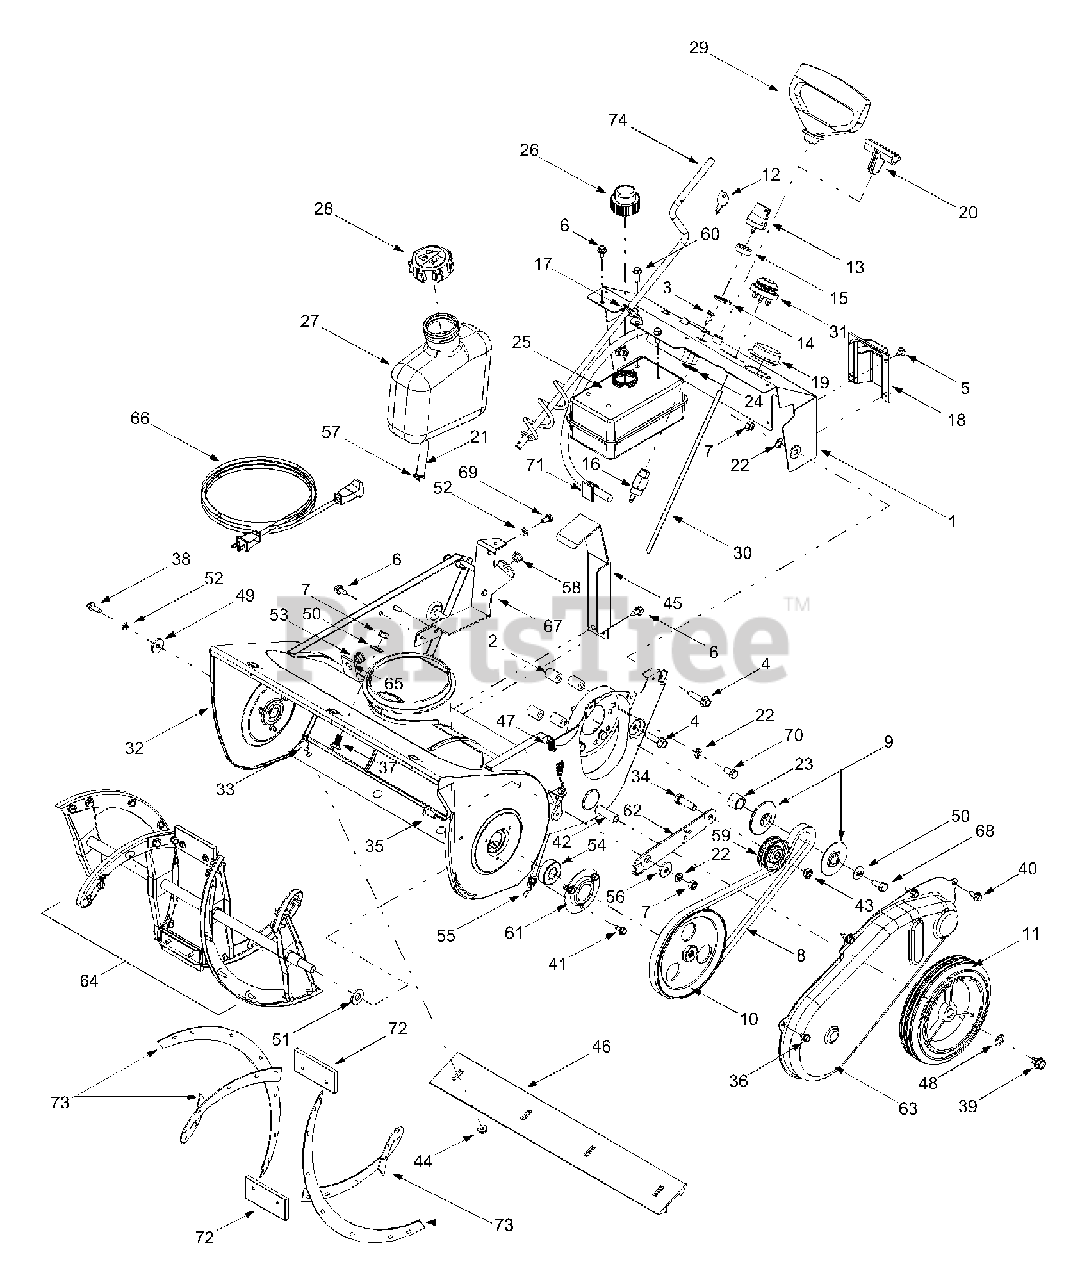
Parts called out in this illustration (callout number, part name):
3	Screw, #10-16 x .625
4	Hex Flange Screw, 5/16-18 x 1.25
5	Screw, #10-16 x .375
6	Self-tapping Screw, 1/4-20 x .625
7	Hex Nut, 5/16-18
8	Drive Belt-Model 150, E150, E162, E172
9	Pulley Half-.625 x 2.25
10	Auger Drive Pulley
11	Wheel Assembly, 7 x 1.5
12	Ignition Key
13	Ignition Key w/ Plastic Cover
14	Ignition Nut, 5/8-32-Model E162, E172
15	Ignition Switch Cap
16	Ignition Switch
17	Chute Crank Bracket-Model 140
18	Choke Cover
19	Spark Plug Cap
20	Recoil Handle (Standard)
21	Fuel Line Hose
22	Lock Washer, 5/16
23	Spacer, .630 x .88 x .680
24	Internal Lock Washer, 5/8 x 1.058 x .046
25	Gas Tank, 1 qt-Model 140
26	Fuel Cap for 751-0352
27	Gas Tank, 2 qt.-Model 150, E150, E162, E172
28	Fuel Cap for 751-0540A
29	Recoil Handle (Mitten Grip)
30	Primer Tube
31	Primer Bulb
34	Cap Screw, 3/8-24 x 1.25
35	Trus Machine Screw, 5/16-18 x .75
36	Hex Index Washer Screw, 1/4-14 x .375
37	Carriage Bolt, 5/16-18 x .75
38	Self-tapping Screw 1/4-20 x .75
39	Self-tapping Screw 3/8-16 x .50
40	Self-tapping Screw, 1/4-14 x .625
41	Self-tapping Screw, 1/4-14 x .50
42	Axle, .35 x .5 x 20.75
43	Jam Lock Nut, 3/8-24
44	Hex Flange Lock Nut, 1/4-20
47	Extension Spring, .33 x 1.12
48	Flat Washer, .51 x .75 x .033
49	Flat Washer, .265 x .938 x .120
50	Belleville Washer, .340 x .872
51	Flat Washer, .51 x 1.0 x .125
52	Lock Washer, 1/4
53	Plastic Bushing
54	Ball Bearing, 17mm x 40mm x 12mm
55	Cable, 41.78"
56	Shoulder Spacer
57	Hose Clamp, .49
58	Plastic Bushing, .38
59	Flat Idler Pulley, 1.88 x .50 x 2.12
60	Hi-Lo Self-tapping Screw, 1/4-15 x .75
69	Hex Cap Screw, 1/4-20 x .50
70	Hex Cap Screw, 5/16-24 x .625 -Model 150, E150, E162, E172
71	Self-adhesive Clamp, .5
72	Rubber Paddle
73	Rubber Paddle/Spiral
74	Chute Crank Assembly-Model 140
